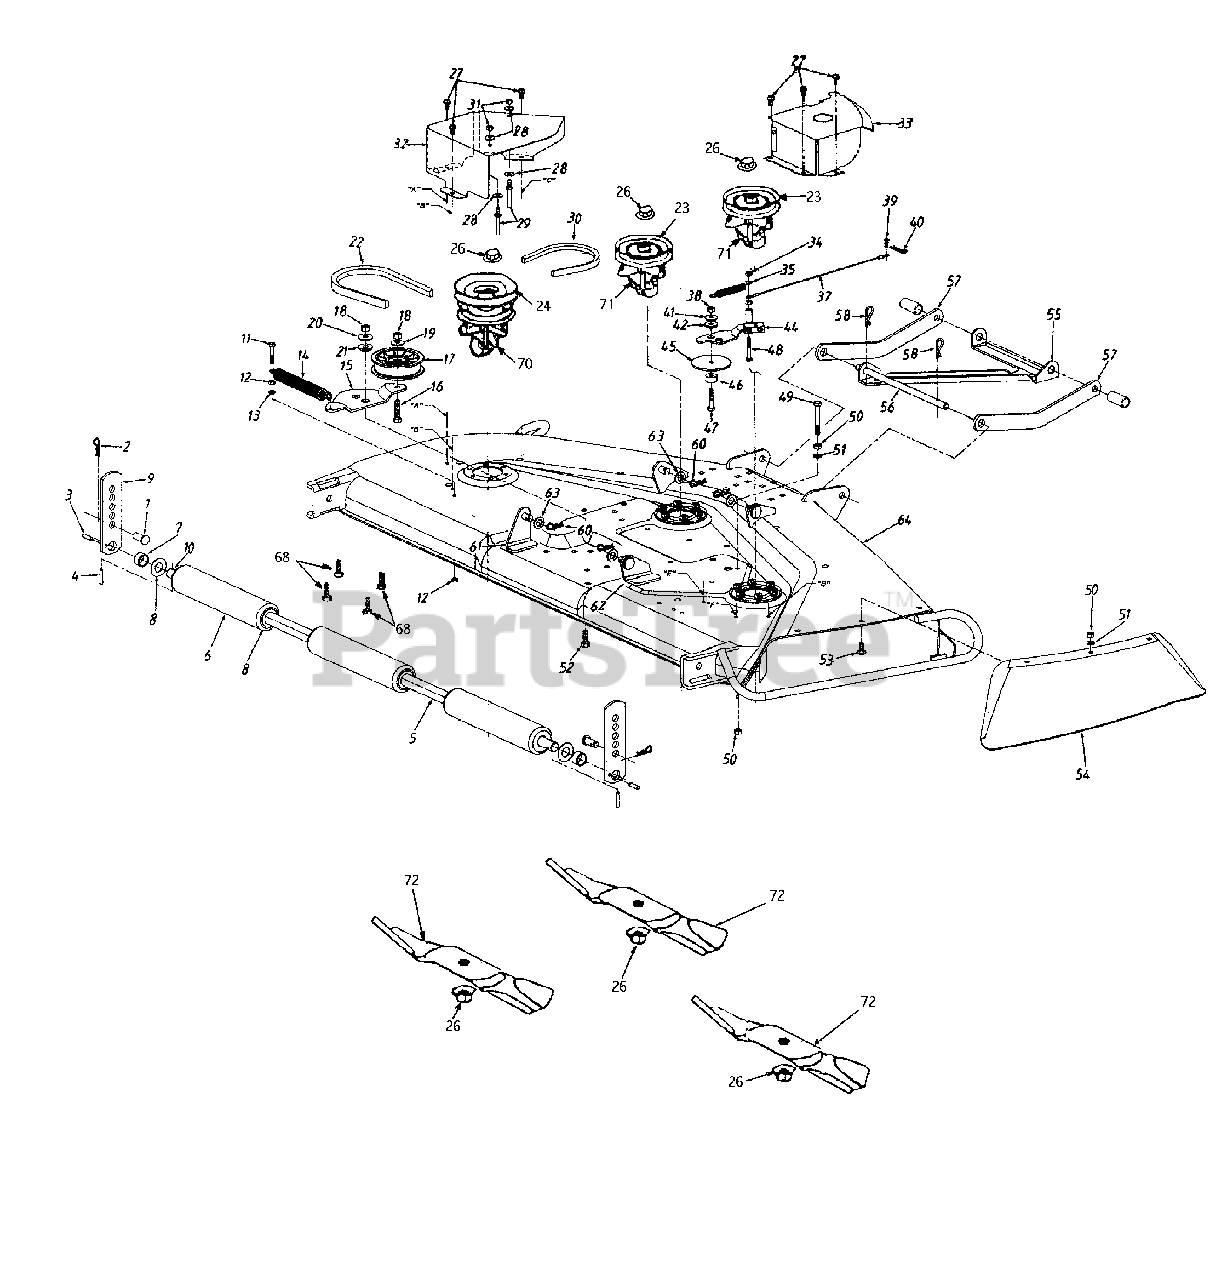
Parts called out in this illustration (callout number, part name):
1	Clevis Pin
2	Hairpin Clip
3	Spring Pin 1/4" x 1" Lg.
4	Spring Pin 3/16" x 1-1/4" Lg.
7	Spacer .75" I.D.
8	Fl-Wash. .76" I.D. x 1.5" O.D.
10	Roller Shaft
11	Hex Bolt 1/4-28 x 1.5" Lg. (Gr. 5)
12	Hex Nut 1/4-28 Thd.
13	L-Wash. 1/4" I.D.
14	Ext. Spring 7.33" Lg.
17	Idler Pulley
18	Hex Nut 3/8-24 Thd.
19	Bell-Wash. 3/8" I.D.
20	Bell-Wash. .39" I.D. x 1.13" O.D.
21	Shld. Spacer .625" I.D.
22	Lower "V"-Belt
23	Deck Pulley
24	Double Deck Pulley
26	Hex Flange Nut 5/8-18 Thd.
27	Hex Wash. Hd. Scr. 1/4-20 x .5" Lg.
28	Bell-Wash. 1/4" I.D.
29	Belt Guard Pin
30	Upper "V"-Belt
31	Hex Nut 1/4-20 Thd.
35	Ext. Spring 3.97" Lg.
37	Brake Cable
38	Hex Nut 5/16-24 Thd.
39	Clevis Pin
40	Hairpin Clip
41	Bell-Wash. .325" I.D.
42	Shld. Spacer
44	Brake Ass'y.
45	Fl-Wash. 5/16" I.D. x .3" O.D.
46	Spacer .44" Lg.
47	Hex Bolt 5/16-24 x 1.5" Lg.(Gr. 5)
48	Hx Bolt 1/4-28 x 1.75" Lg. (Gr. 5)
49	Hex Bolt 5/16-18 x 2.5" Lg.
50	Hex Nut 5/16-18 Thd.
51	L-Wash. 5/16" I.D.
52	Hex Bolt 3/8-24 x 1" Lg.
53	Carr. Bolt 5/16-18 x .75" Lg.
60	Hairpin Clip
63	Fl-Wash. 1/2" I.D. x .93" O.D.
70	Spindle Ass'y. (L.H.)
71	Spindle Ass'y. (R.H. & Center)
72	Blade
